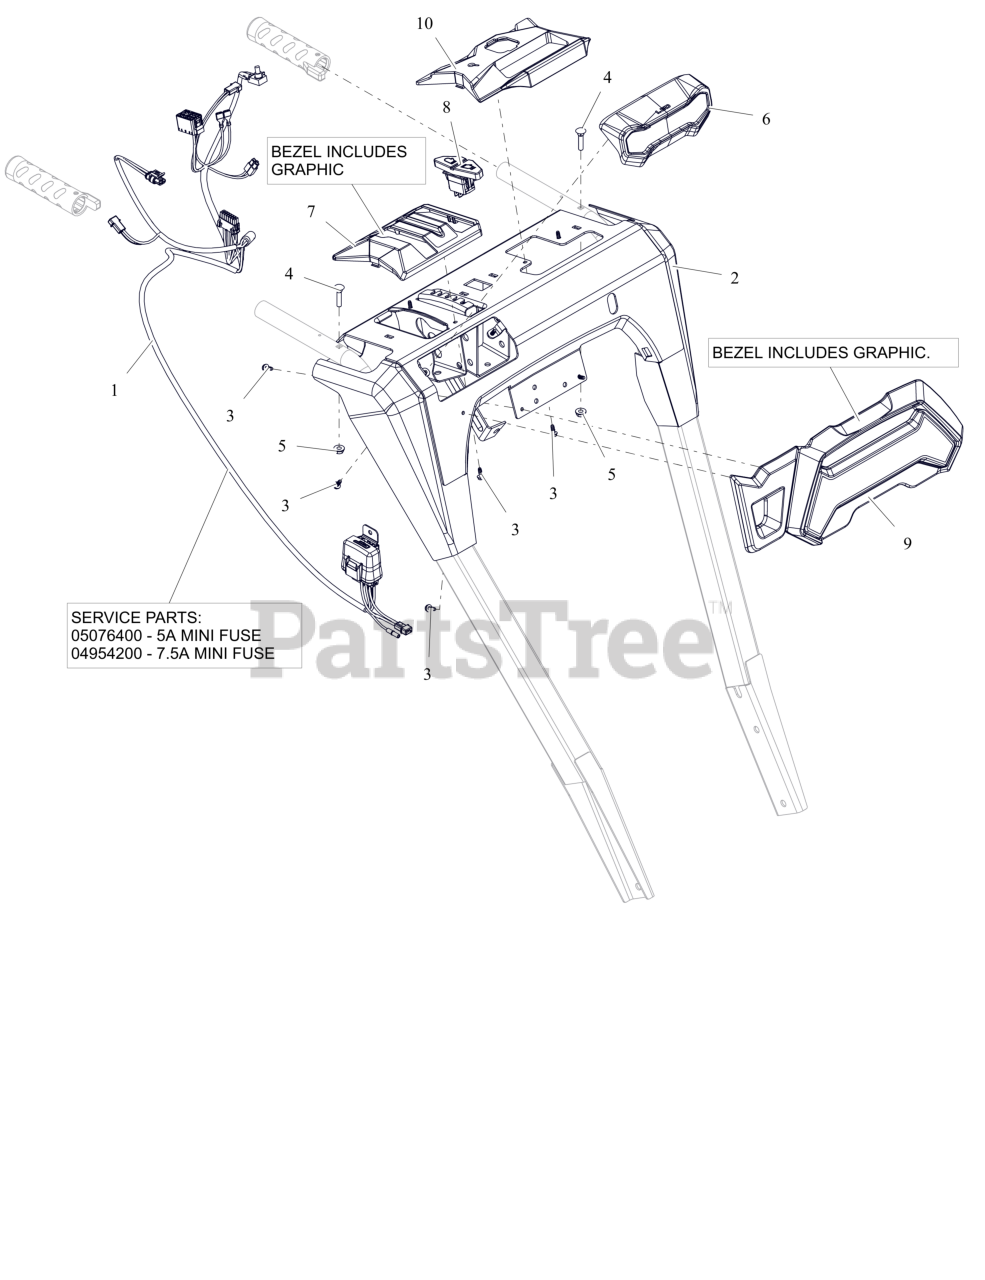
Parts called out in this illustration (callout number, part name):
1	HARNESS- WIRE - LT HG EFI
1	FUSE, 5 AMP MINI-ATC
1	FUSE, 7.5 AMP MINI-ATC
2	PANEL, DASH-HYDRO EFI W/DECAL
3	SCR, PLASTIC #10X.50
4	BLT-RDHDXLSQNK.25-20X1.25 G5ZC
5	NUT-LK-CTR-FLG .25-20 ZC120
6	HEADLIGHT ASM- LED
7	BEZEL, SHIFT - HYDRO
8	SWITCH- ROCKER SPST-ON/OFF
9	BEZEL- LARGE - PROFESSIONAL
10	BEZEL, OPERATOR EFI CHUTE DECAL
